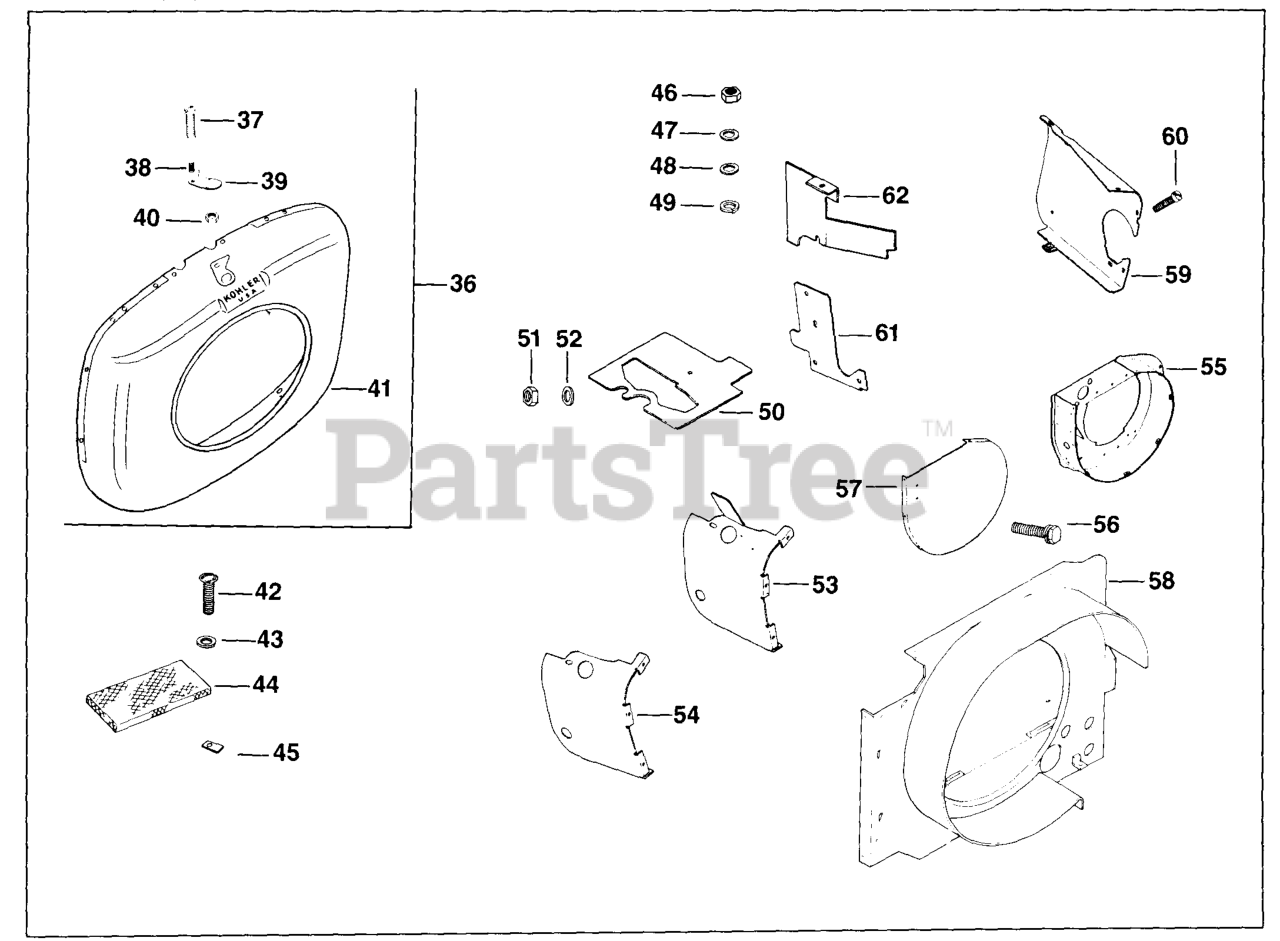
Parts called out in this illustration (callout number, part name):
46	NUT, 1/4-20 GRADE 2 USE 25 100 20-S
47	WASHER, FLAT 1/4" (O.D. 1")
48	WASHER, FLAT 1/4" (O.D. 5/8")
49	WASHER, SPRING LOCK 1/4"
51	NUT, 3/8-16 GRADE 2 USE 25 100 26-S
52	WASHER - DISCONTINUED
54	BAFFLE,NO.1 CYL HEAD - DISC.
58	SCROLL ASSEMBLY - DISC.
59	BAFFLE, #2 CYLINDER HEAD
60	SCREW, WSH HD TAP 1/4-20X7/16" USE 25 086 106-S
61	BAFFLE, CYLINDER BARREL - DISC.
62	BAFFLE, TOP CYL.BARREL 2-DISC.
